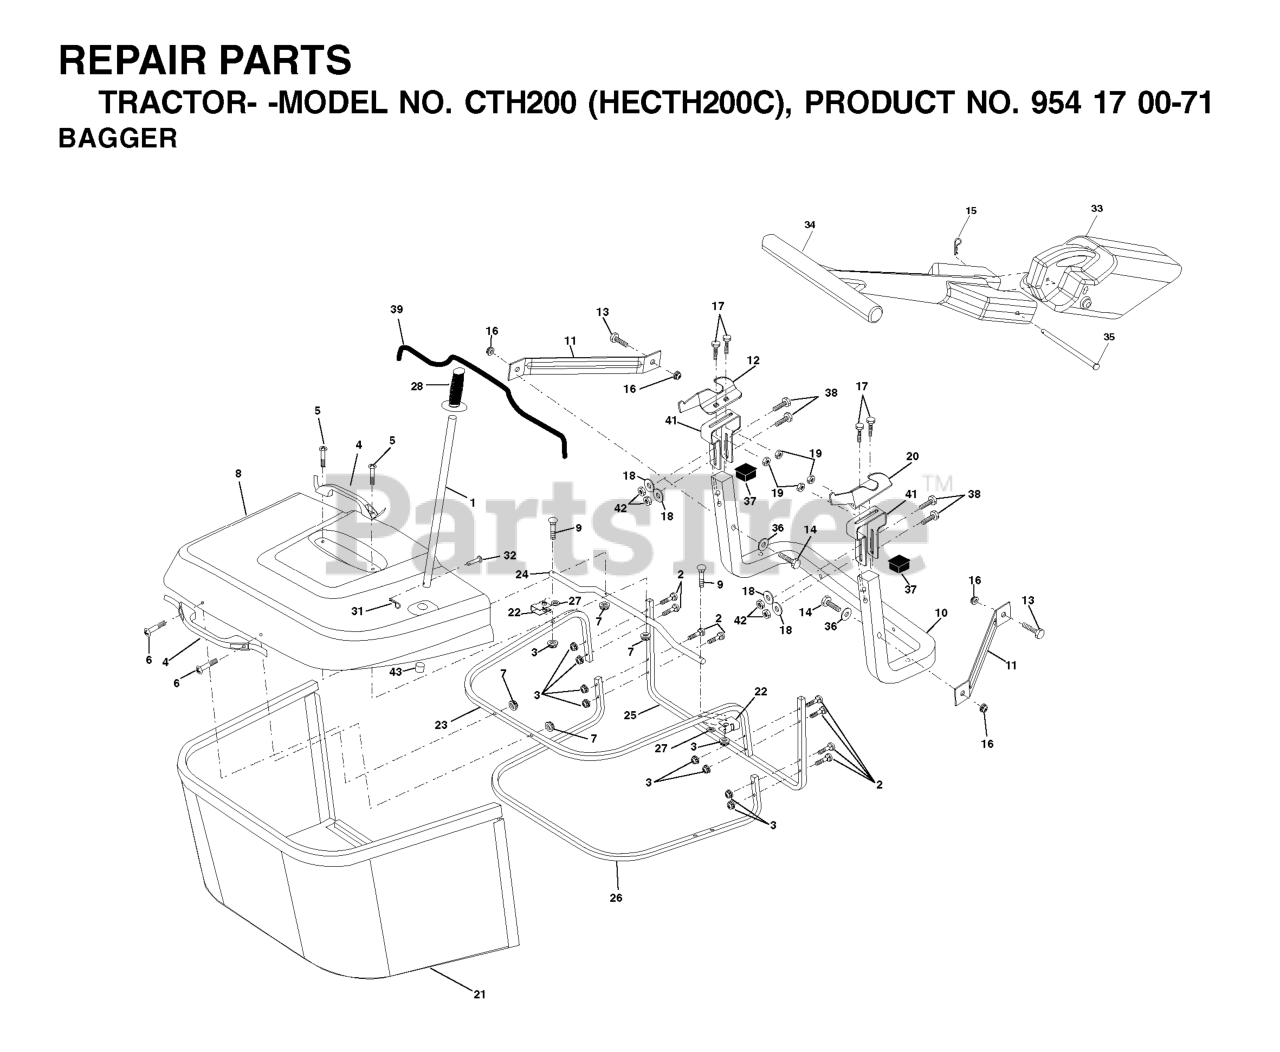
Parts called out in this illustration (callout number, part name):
1	TUBE HANDLE
2	Bolt Carriage 1/4-20 x 2.0 Gr.5
3	NUT T
4	HANDLE.BAGGER.W/LVRS.BLK.CRD
5	SCREW.PAN.HEAD
6	REPL BY 532 75 00-29
8	COVER.PNT.BGR.CRD.WSLOTS.MS668
9	Bolt Carriage 1/4-20 x 2.25d x Gr.5
10	TUBE
11	BRACKET.SUPPORT.UPPER.BAG.CRD
14	BOLT-HEX EAK
15	RETAINER-SPRNG RB
16	NUT LOCK FLG 3/8-16 UNC
17	RP BOLT 5/16-18 X3/4 ZN/YEL GR
18	WASHER M
19	NUT LOCK HEX FLANGE 5/16-18
20	BRACKET
21	GRASS BAG
22	BRKT.SIDE.BAG.CRD
23	TUBE.UPPER.BAG.CRD
24	TUBE.PIVOT.BAG.CRD.BLACK
26	TUBE.LOWER.BAG.CRD
28	GRIP.HANDLE.BLACK
31	RETAINER M
32	RIVET,DRILLED
33	MULCH PLUG, CTH150
34	HANDLE.MULCHER.92.CRD (2 2)
36	WASHER
37	Plug Support Bagger CRD
38	BOLT.5/16-18X2.5
39	SEAL.TRIM.37'
41	BRKT.VERT.ADJ.BAGGER.CRD
42	NUT.71038.31-18.HEX.NYLOCK
43	PLUG, TUBING END
